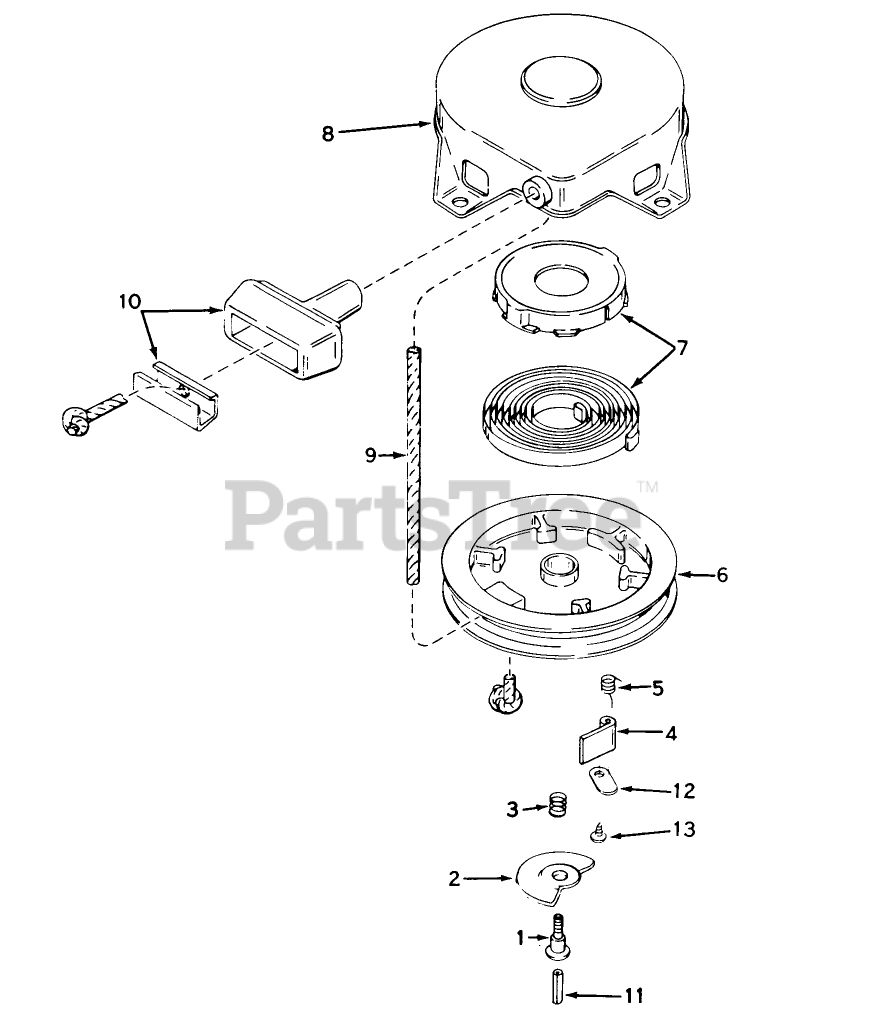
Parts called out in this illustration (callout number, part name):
1	Screw
2	Cam-Dog
3	Spring-Brake
4	Dog-Starter
5	Spring-Dog
6	Pulley
7	Spring Keeper Assy
8	STARTER HOUSING ASSY
9	Rope-Starter
10	Assy., Starter
11	Centering
12	Retainer-Dog
13	Screw
